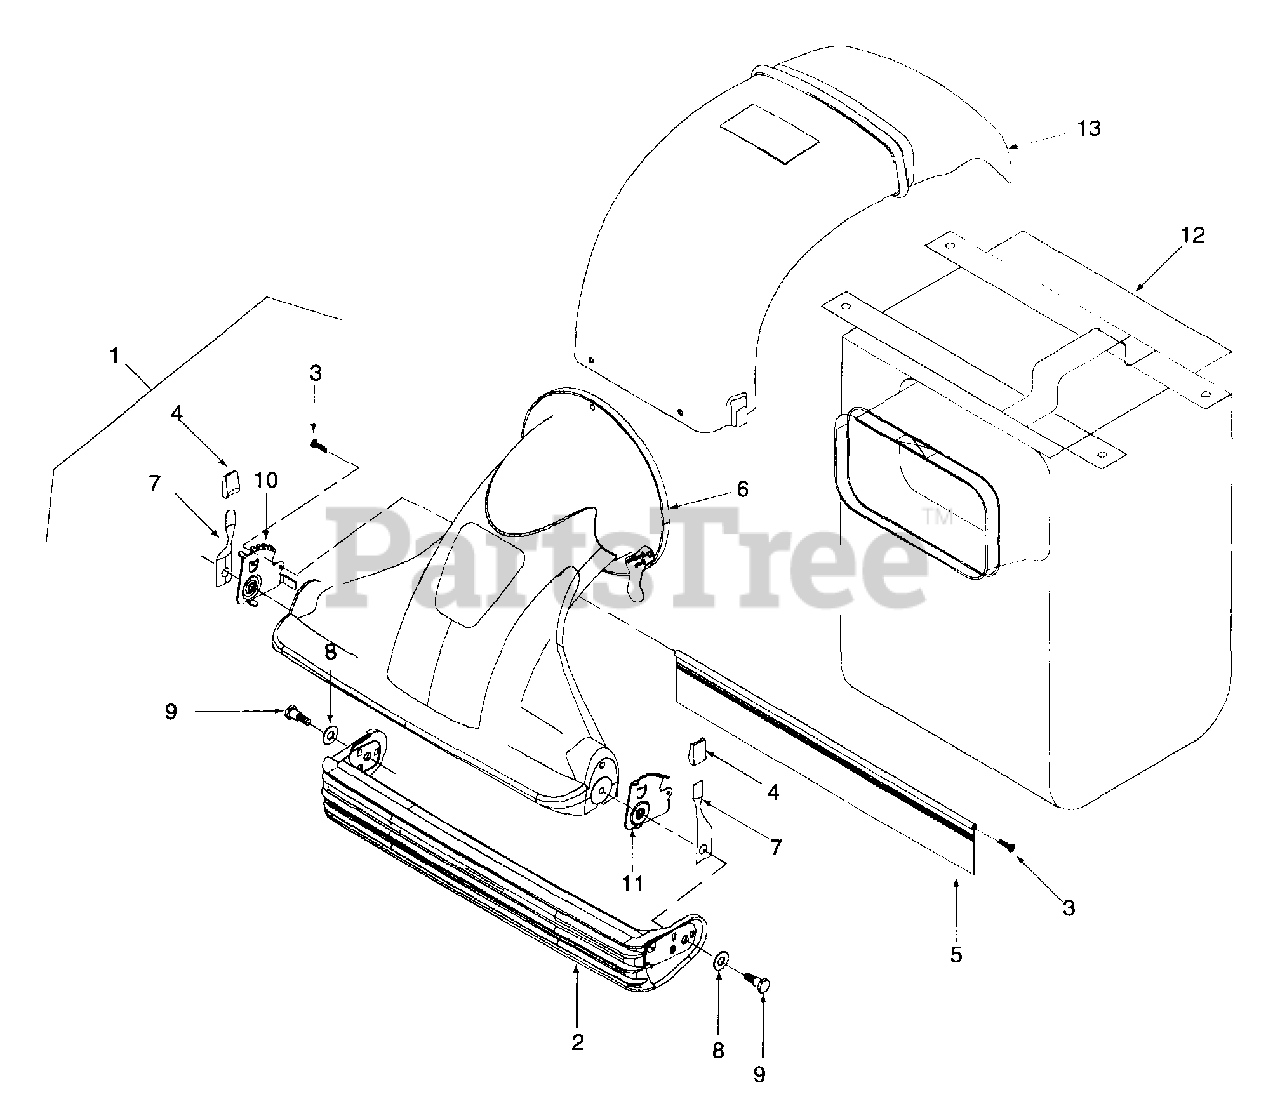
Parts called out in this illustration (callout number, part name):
1	Nozzle Assembly Complete
2	Door Assembly, Black
3	Screw, Truss Hd Tapp
4	Knob, Height Adj.
5	Flap, Nozzle Rear
6	Nozzle, Black, w/ Switch Bracket
7	Spring Lever
8	Washer, Flat, .510 x 1.20 x .060
9	Screw, Shoulder, .50 x 5/8-16
12	Bag, 3 Bushel
13	Discharge Chute
